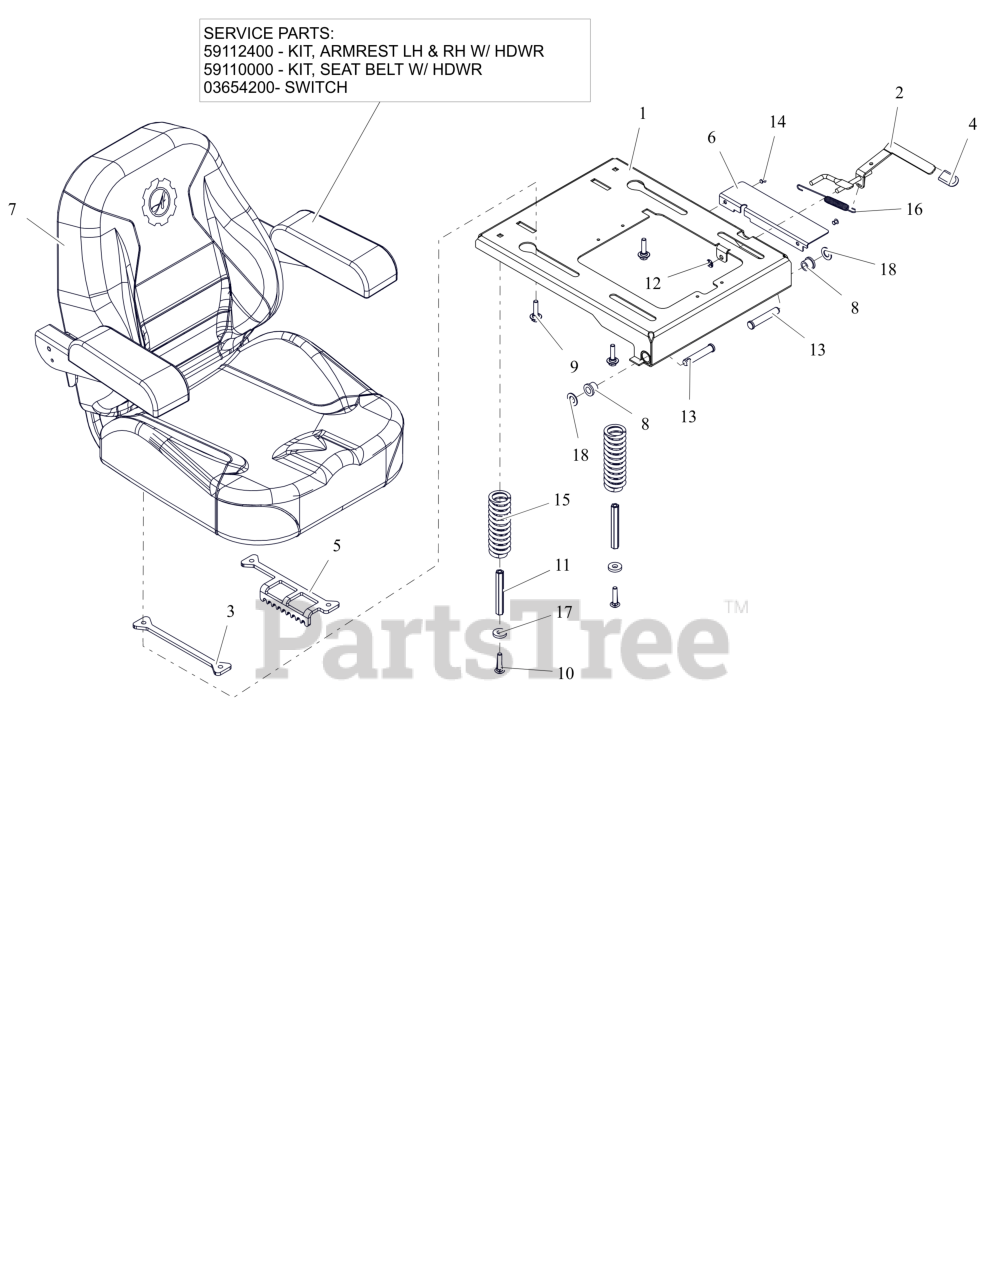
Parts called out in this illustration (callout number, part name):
1	WLDMT, SEAT PLATE HD
2	WLDMT, SEAT SLIDE LEVER
3	PLATE, ADJ SEAT SLIDE (BLACK)
4	GRIP, SEAT LEVER, GREY
5	PLATE, SEAT ADJ (BLACK)
6	GUARD, SEAT PLATE
7	SEAT, APEX
7	KIT-LH & RH ARM REST-05124700
7	KIT-SEAT BELT REPLACE-05007300
7	SWITCH- SEAT
8	BSHG, FLG .516X.750X.625X.937
9	BOLT SHLDR .31-18 X .175
10	BLT,RHSN .31-18X1.50 G5 ZCC
11	NUT, COUPLING 5/16X18 X 3.75
12	NUT-PUSH .312
13	PIN-CLIC .50X2.70X2.31 -ZCC
14	RIVET, .1875 AL/AL .126-.250
15	SPRING, COMPRESSION SEAT 224LB
16	SG-TENS .06X.482X5.35
17	WSHR, FLT .406X1.00X.188 ZCC
18	WSHR, FLT .531X1.00X.063 ZCC
